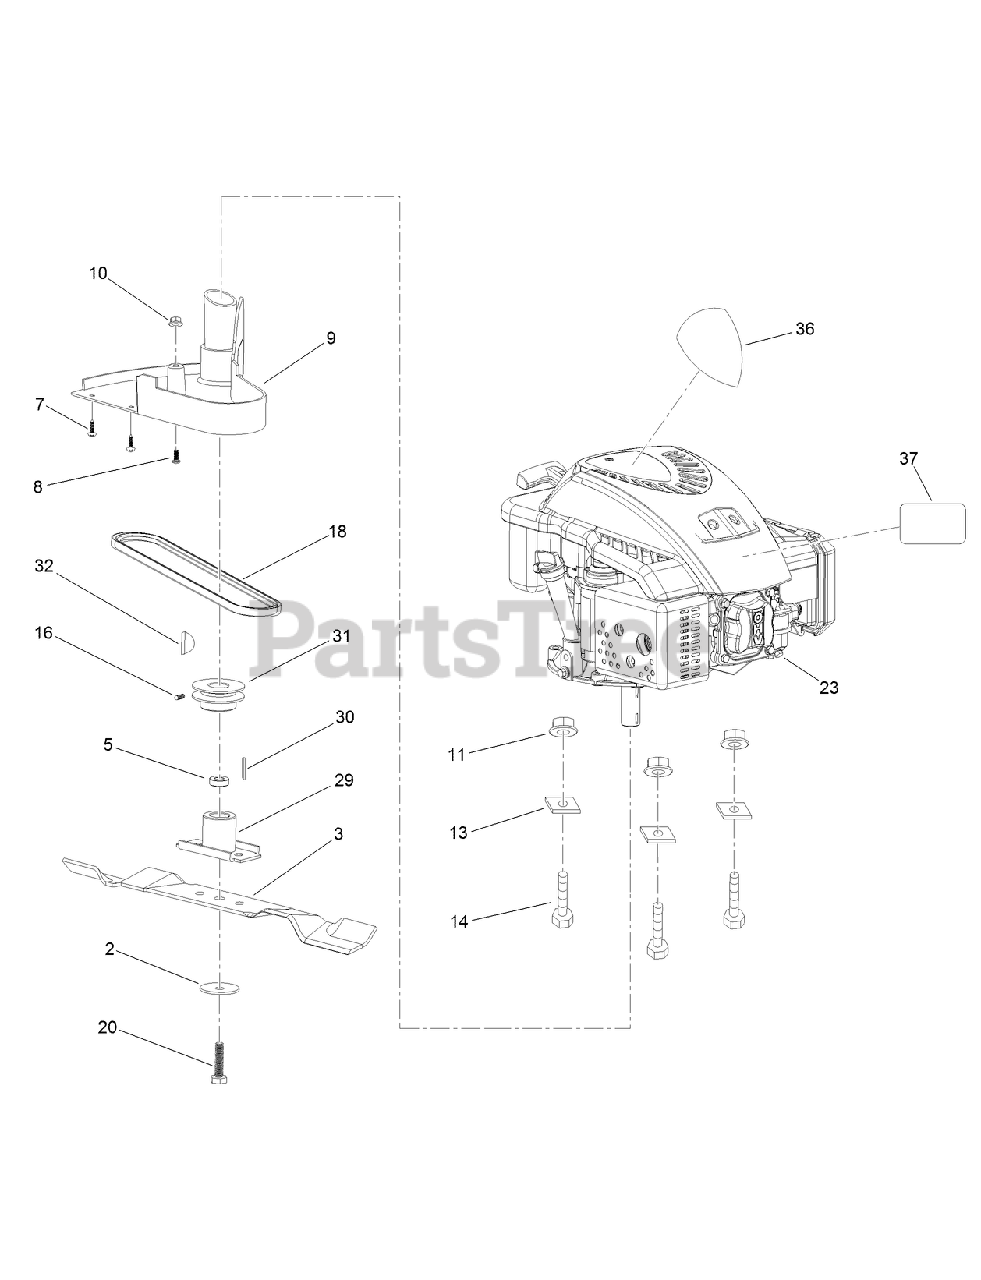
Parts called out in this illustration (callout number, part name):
2	WASHER-DISHED
3	BLADE-MULCH
5	SHEATH-BLADE
7	SCREW-SELF DRIVING
8	SCREW-TOOTH
9	COVER-PULLEY, BELT
10	NUT-LOCK, FLANGE
11	NUT-LOCK, FLANGE
13	WASHER-SQUARE
14	BOLT-BLADE
16	SCREW-GRUB
18	BELT-TRIANGLE
20	BOLT-BLADE
23	ENGINE-1P65FA, RECOIL
29	SUPPORT-BLADE
30	KEY-FLAT
31	PULLEY-DRIVE
32	KEY-WOODRUFF
36	DECAL-SHROUD
37	PLATE-LOGO
